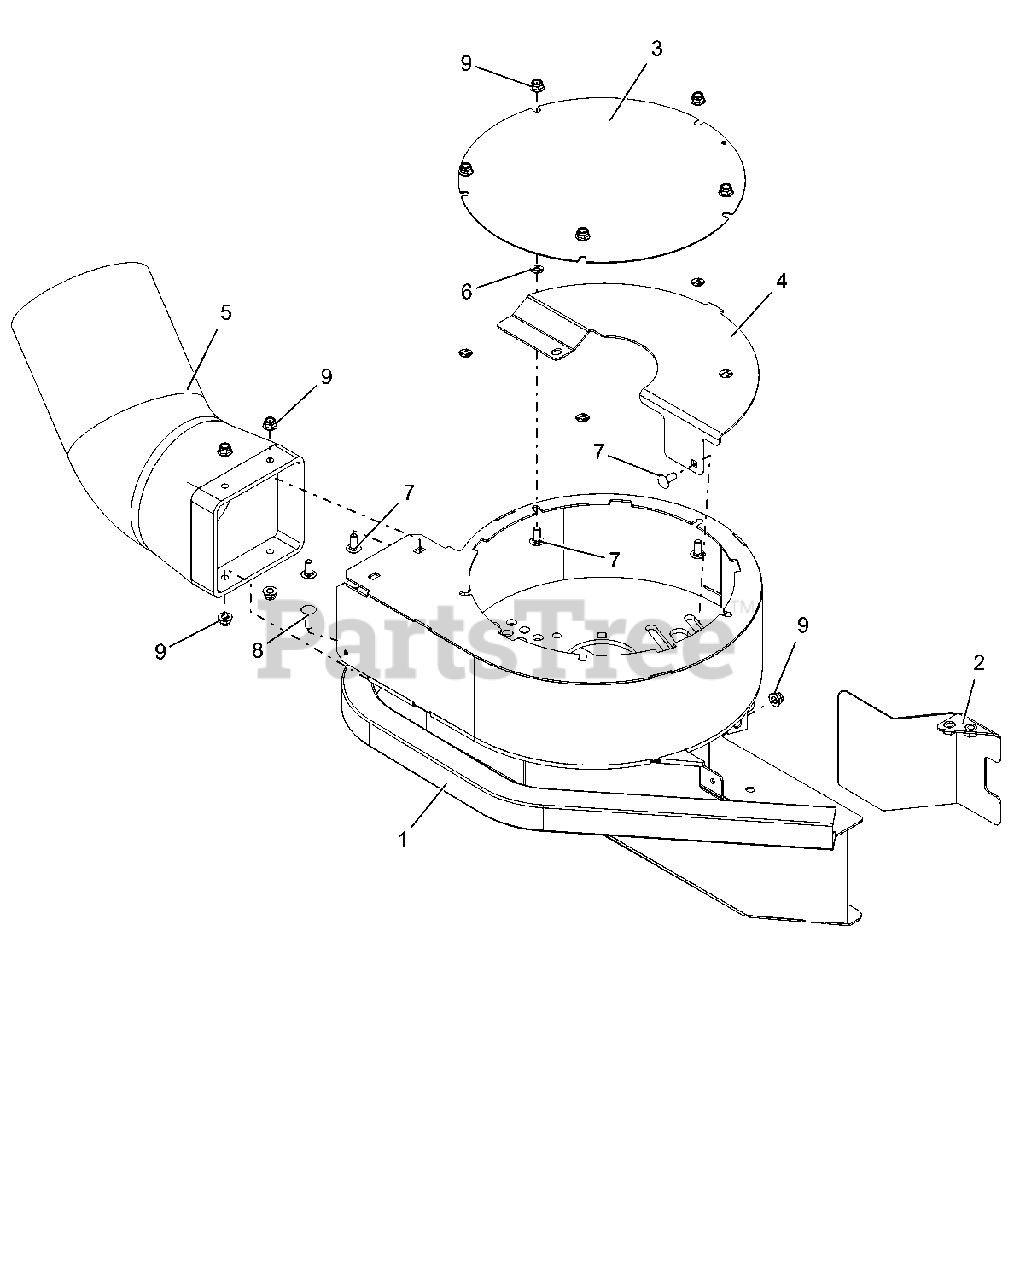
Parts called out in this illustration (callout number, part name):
1	BLOWER ASSEMBLY, SERVICE
1	COMM BAGGER BLOWER WLDMT - RED
2	60" FRT BLOWER BAFFLE WMT -BLK
3	COVER, BLOWER-RED
4	COVER, BOTTOM
5	ADAPTER-HOSE 52/60"
6	NUT-PUSH .312
7	@BLT-RHDSSQNK .31-18X.75 G5YZ
8	@BLT-RHDSSQNK .31-18X1.00 G5YZ
9	@NUT-LK-NYL-FLG .31-18 YWZC
